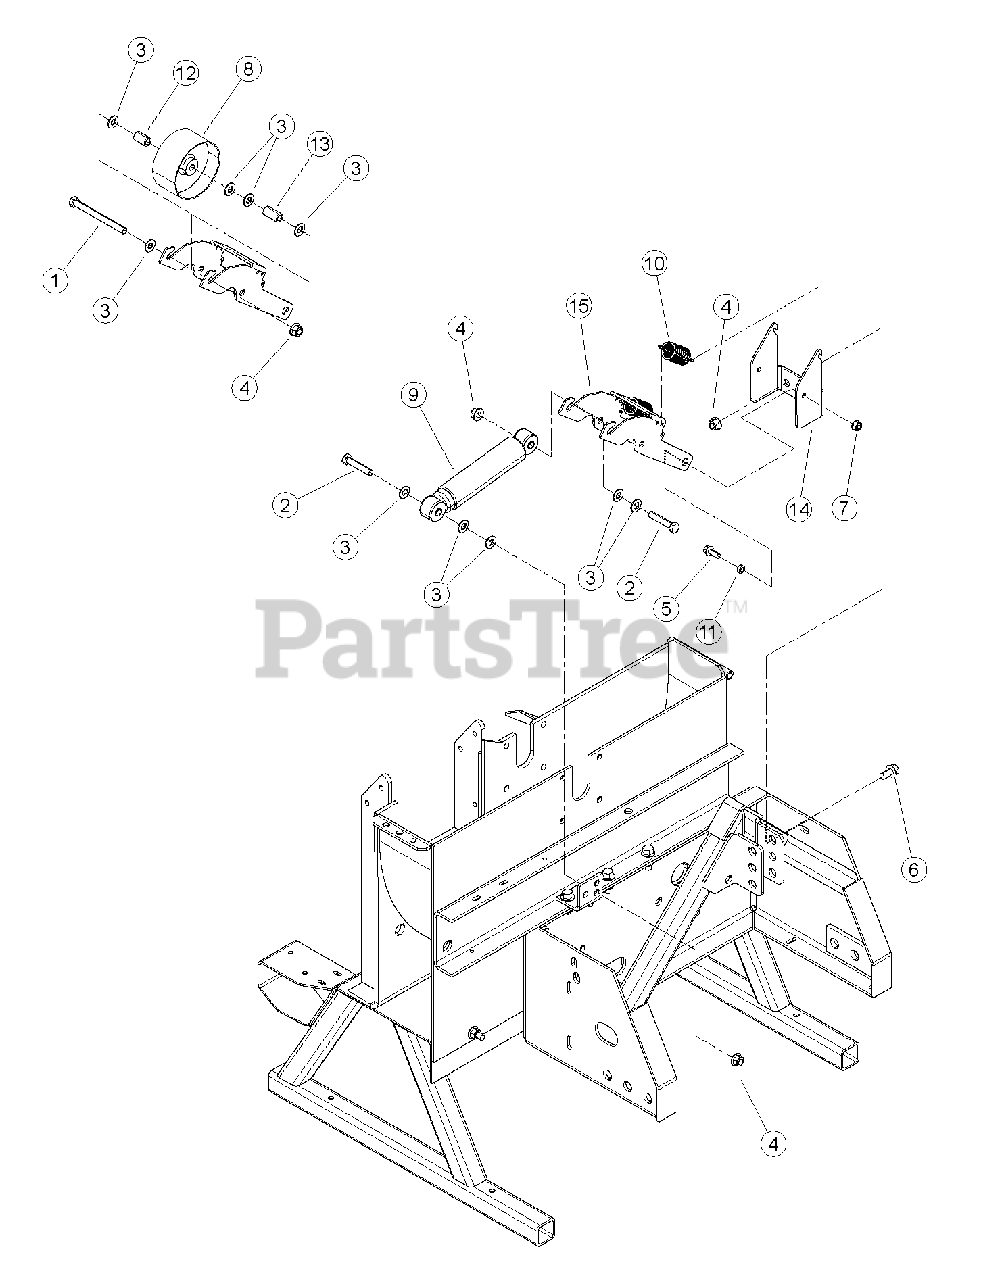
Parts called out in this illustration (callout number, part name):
1	BOLT, 1/2 X 5-1/2 HEX GR5 ZP
2	BOLT, 1/2 X 2-1/2 GR5 HEX CAP ZP
3	WASHER, 1/2"SAE FLAT ZP
4	NUT, 1/2-13 NYLOCK FLANGE
5	BOLT, 3/8 X 1 FLANGE NC
6	BOLT, 1/2 -13 X 1-1/4 FLANGE NC
7	NUT, 3/8-16 NYLOCK FLANGE
8	PULLEY, IDLER 5 X 2.50"
9	ABSORBER, IDLER SHOCK
10	SPRING, 1.25 OD X 3.50 LG X .148 WD
11	SPACER, IDLER PIVOT
12	SPACER, .75 X 1.18
13	SPACER, .75 X 1.47
14	BRACKET, INSIDE IDLER MOUNTING
15	ARM, INSIDE IDLER
